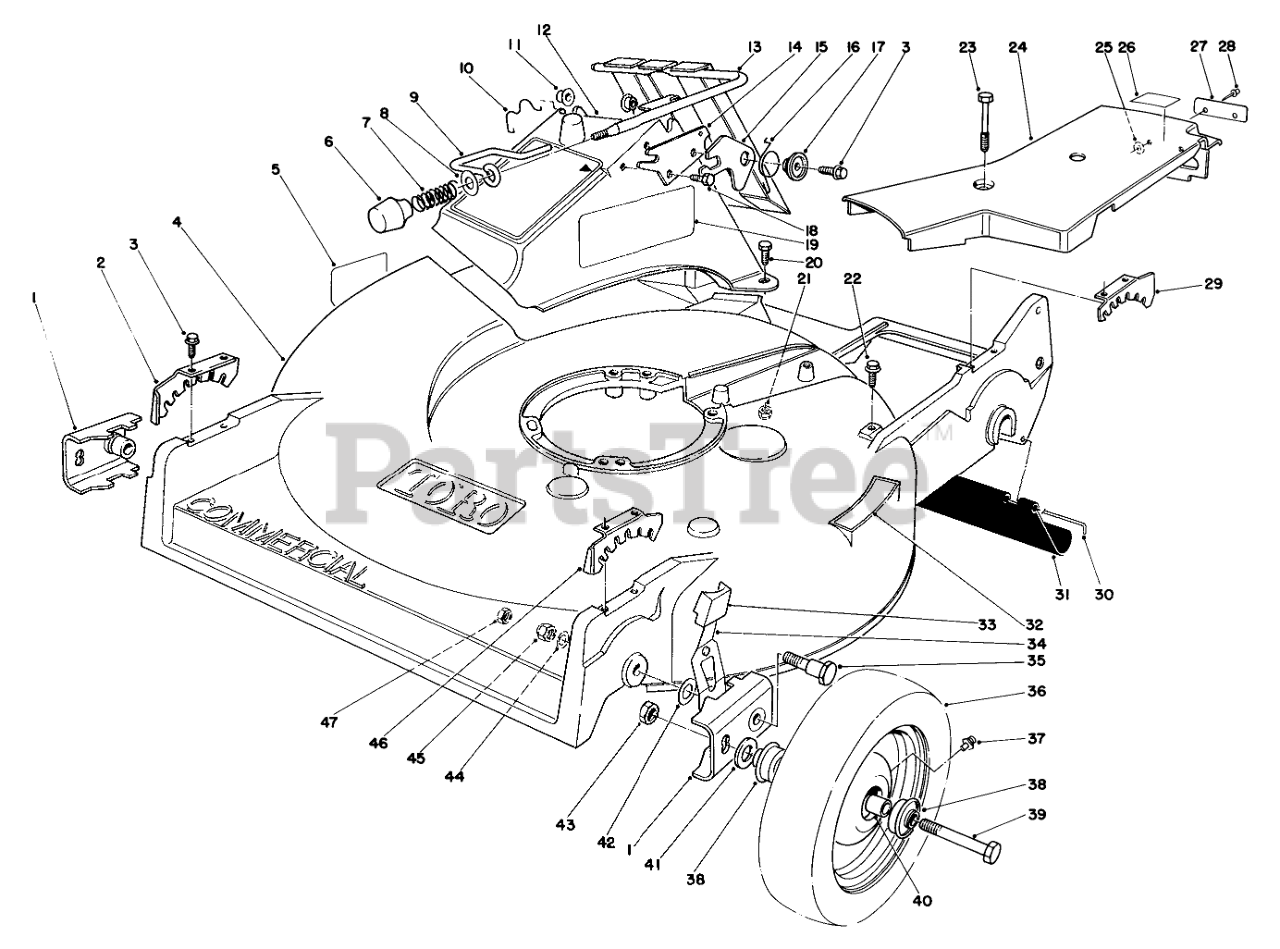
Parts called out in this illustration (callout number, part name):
1	PIVOT ARM ASM
2	RH QUADRANT
3	Screw
4	Housing
5	DECAL-DANGER
7	COMPRESSION SPRING
8	WASHER-FLAT
9	DOOR LATCH
10	DOOR RETAINER
11	BUSHING-NYLON
12	Chute & Door Assembly (Incl. Ref. #3, 6-11 & 13-21)
13	DOOR & HANDLE WA
14	DOOR LATCH PLATE
15	SAFETY LATCH
16	TORSION SPRING
17	DOOR SPACER
18	SCREW-HWH
19	DECAL SAF INST
20	SCREW-HH
21	NUT-LOCK, NI
22	SCREW-HWHTF
23	SCREW-HHFTF
24	Belt Cover Assembly (Incl. Ref. #25, 27 & 28)
25	WASHER-PLAIN
26	Label-Grease
27	NAMEPLATE-GRD SPEED
29	Quadrant-Rear L.H.
30	ROD-SHIELD
31	SHIELD-TRAILING
32	STEP PAD DECAL
33	KNOB-ARM
34	Spring Arm
35	PIVOT SCREW
36	Wheel & Tire Assembly (Incl. Ref. #37-38 & 40)
37	FITTING-GREASE
38	Bearing-Flanged
39	SCREW-HH
40	Spacer-Wheel Bearing
41	WHEEL SPACER-HP
42	WASHER-PIVOT
43	NUT-LOCK, CONE
44	WASHER-PLAIN
45	NUT-LOCK, NI
46	LH QUADRANT
47	NUT-JAM
